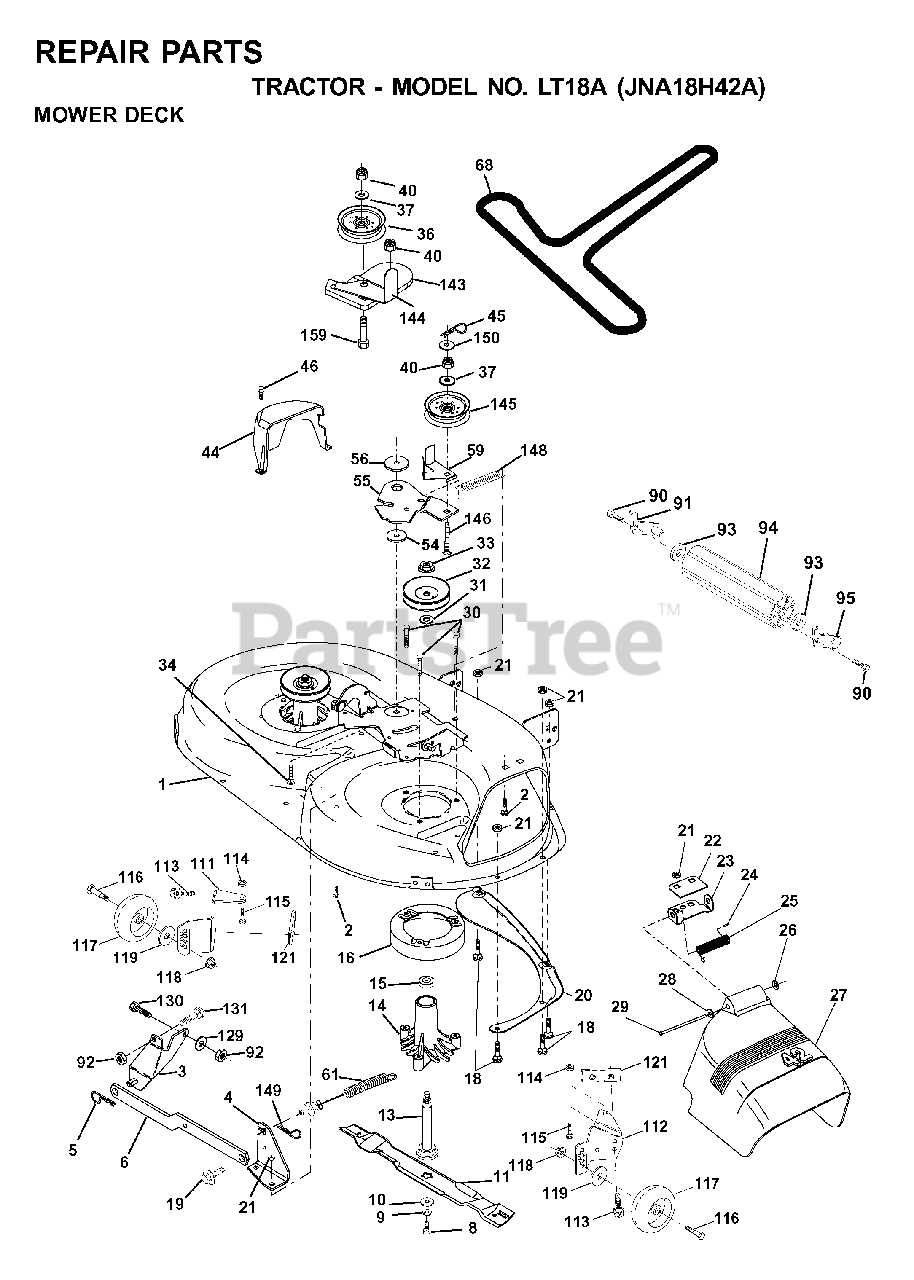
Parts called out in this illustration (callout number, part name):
1	42" DECK KIT
2	BOLT
3	BRKT ASM SWAY BAR
4	BRACKET SWAY BAR 42" DECK
5	RETAINER-SPRNG RB
6	REAR SUSP ARM
8	BLADE BOLT
9	LOCKWASHER
10	WASHER.BLADE
11	BLADE 42"
13	SHAFT ASM VENT
14	HSG MANDREL
16	STRIPPER, MWR ROUND
18	BOLT
19	BOLT SHD 5/16-18
20	BAFFLE.VORTEX
21	LOCKNUT
22	STIFFENER BRACKET
23	DEFLECTOR BRACKET
24	CAP-SLEEVE LT
25	SPRING TORSION
26	NUT PUSH M
27	SHIELD DEFLECTOR
28	WASHER
29	ROD.HINGE
30	SCREW THDROL ROLLING WASHER HD
31	WASHER
32	PULLEY/MANDREL
33	NUT
34	BOLT
36	FLAT IDLER PULLEY
40	LOCKNUT
44	GUARD MANDREL LH BLACK
45	RETAINER M
46	SCREW.1/4-20X5/8
54	HARDENED WASHER
56	SPACER.RETAINER.MOWER
59	GUARD, BELT
61	SPRING EXT ELEC CLUTCH
68	V-BELT PRIMARY 42"
90	SCREW
91	BRACKET ASM, ROLLER (L)
92	NUT
94	NOSE ROLLER
95	BRACKET ASM, ROLLER (R)
111	BRACKET WHEEL GAUGE LH 42" DK
112	BRACKET WHEEL GAUGE RH 42" DK
114	NUT
115	BOLT
116	PEDAL COVER T
117	WHEEL.GAUGE.STANDARD
118	LOCKNUT
119	WASHER
121	BRACKET.EXTRD.GWL
129	WASHER
131	BOLT D
143	BRACKET, ARM IDLER
144	KEEPER.BELT.42".CLUTCH.CABLE
145	PULLEY
146	BOLT, CARRIAGE IDLER BLACK
148	IDLER RETURN SPRING
149	SPRING.RETAINER.YELLOW.ZINC
150	WASHER PM
159	BOLT
532134149	BLADE.42".MULCH
